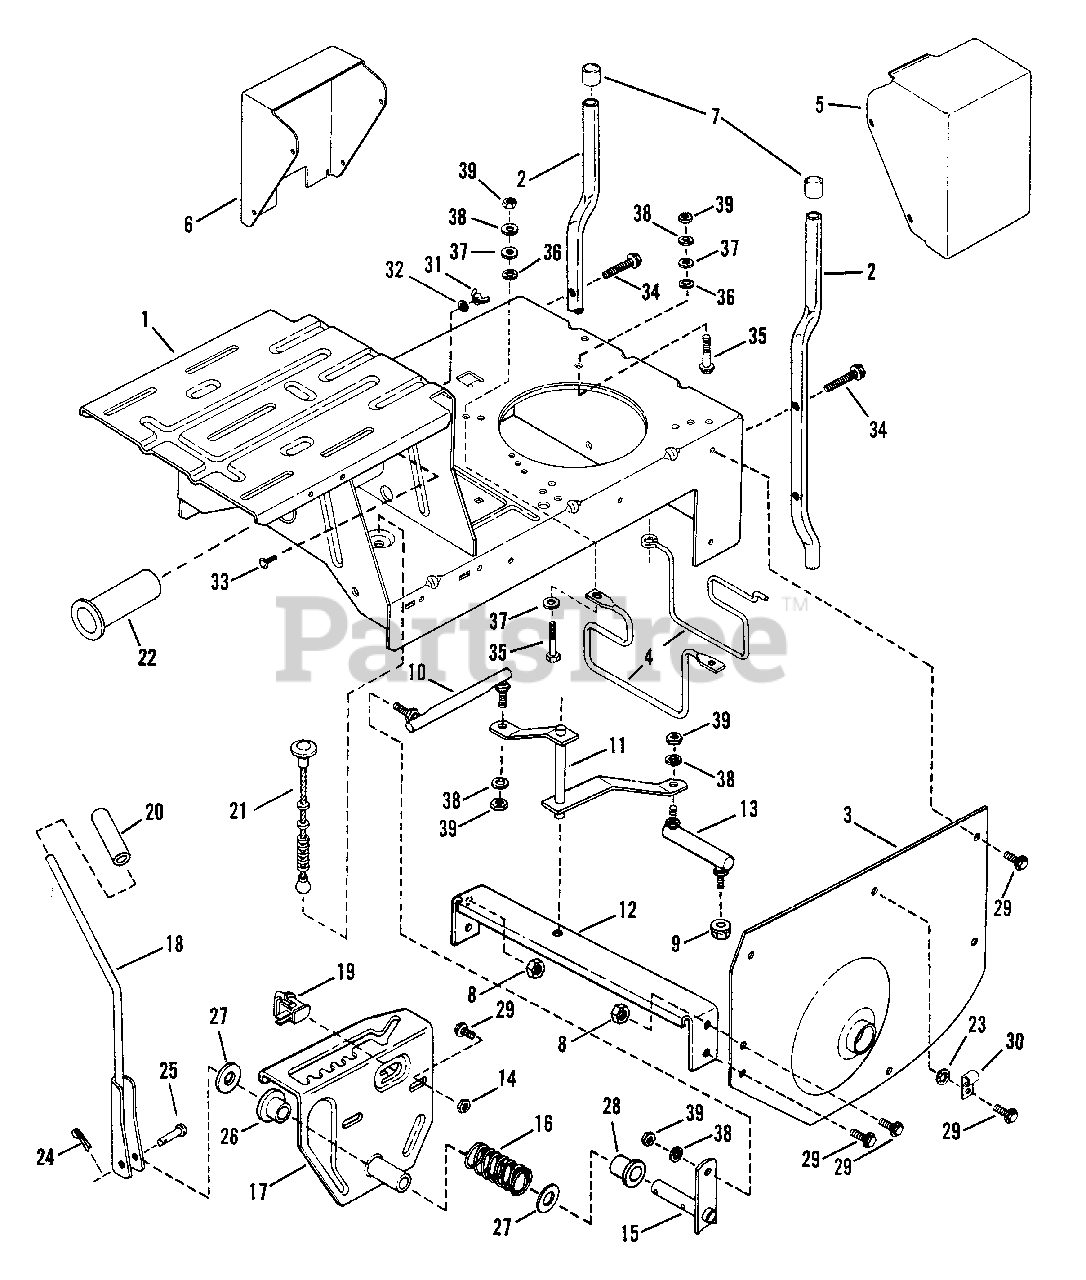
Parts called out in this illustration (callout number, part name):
1	CASE, Main
2	BUMPER, Rear
3	FENDER, Left Hand
4	GUIDE, Belt
5	COVER, Battery
6	COVER, Switch
7	CAP, Bumper
8	NUT, 5/16-18 Hex Flange Lock
9	NUT, 5/16-24 Hex Flange Lock
10	LINK, Shift (Long)
11	ARM, Shift
12	BRACE, Cross
13	LINK, Shift (Short)
14	NUT, 5/16-18 Hex
15	ARM, Shift Handle
16	SPRING, Shift Handle
17	DETENT,Shift
18	HANDLE, Shift
19	SWITCH, Seat
20	GRIP, Shift Handle
21	CABLE, Deck Support 5", 7 Furrels
22	BUSHING, Pilot
23	WASHER, 5/16 Internal Tooth Lock
24	PIN, 3/32 x 3/4" Cotter
25	PIN, 1/4 x 1-3/4" Tapered Clevis
26	BUSHING, Nylon
27	WASHER, Thrust
28	BUSHING, Nylon
29	SCREW, 5/16-18 x 5/8" Self-Tapping
30	CLIP, Wire
31	NUT, #10-24 Locking Wing
32	RETAINER, #10 Bolt
33	FASTENER, 1/4 x 3/4" Ratchet
34	SCREW, 5/16-18 x 1-1/2" Self-Tapping
35	SCREW, 5/16-24 x 1-1/2" Hex Head Cap
35	SCREW, 5/16-24 x 1-3/4" Hex Head Cap
36	RETAINER, 5/16 Bolt
37	WASHER, 5/16" Flat
38	WASHER, 5/16" Split Lock
39	NUT, 5/16-24 Hex
